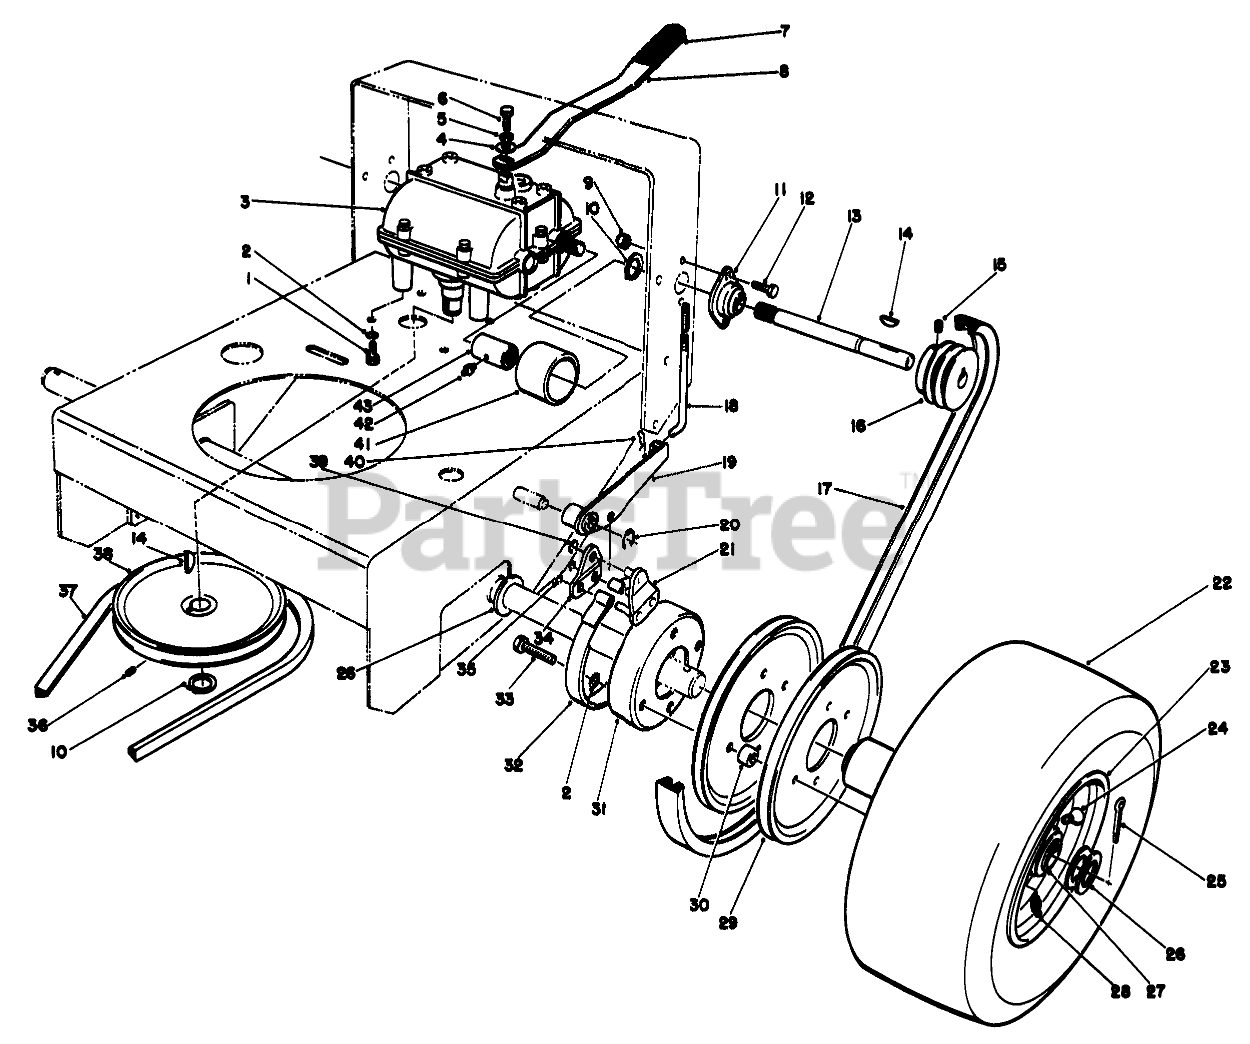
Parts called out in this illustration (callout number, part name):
1	SCREW-HH
2	WASHER-LOCK
3	Transmission
4	SPACER
5	WASHER-LOCK
6	SCREW-HH
8	LEVER-SHIFT
9	NUT-LOCK, NI
10	RING-SNAP, EXTERNAL
11	BEARING-EXTERNAL SHAFT
12	SCREW-HH
13	SHAFT-EXTENSION, LH
14	KEY-WOODRUFF
15	SCREW-SET, HSH
16	Pulley-Drive
17	V-BELT
18	ROD-BRAKE
19	Brake Arm-LH
20	RING-RETAINING
21	LINK-Brake
23	WHEEL AND HUB ASM
24	STEM-VALVE
25	PIN-COTTER
26	WASHER-WHEEL
27	BEARING-BALL, FLANGED
28	FITTING-LUBE, 45 DEG
29	Pulley-Wheel
30	SPACER-PULLEY
31	Drum-Brake
32	BAND-BRAKE
33	SCREW-HH
34	Plate-Link
35	RING-RETAINING
36	SCREW-SET
37	V-BELT
38	PULLEY-DRIVEN
39	RING-RETAINING, EXTERNAL
40	PIN-COTTER
41	GUARD-COUPLER
42	FITTING-GREASE
43	COUPLER
